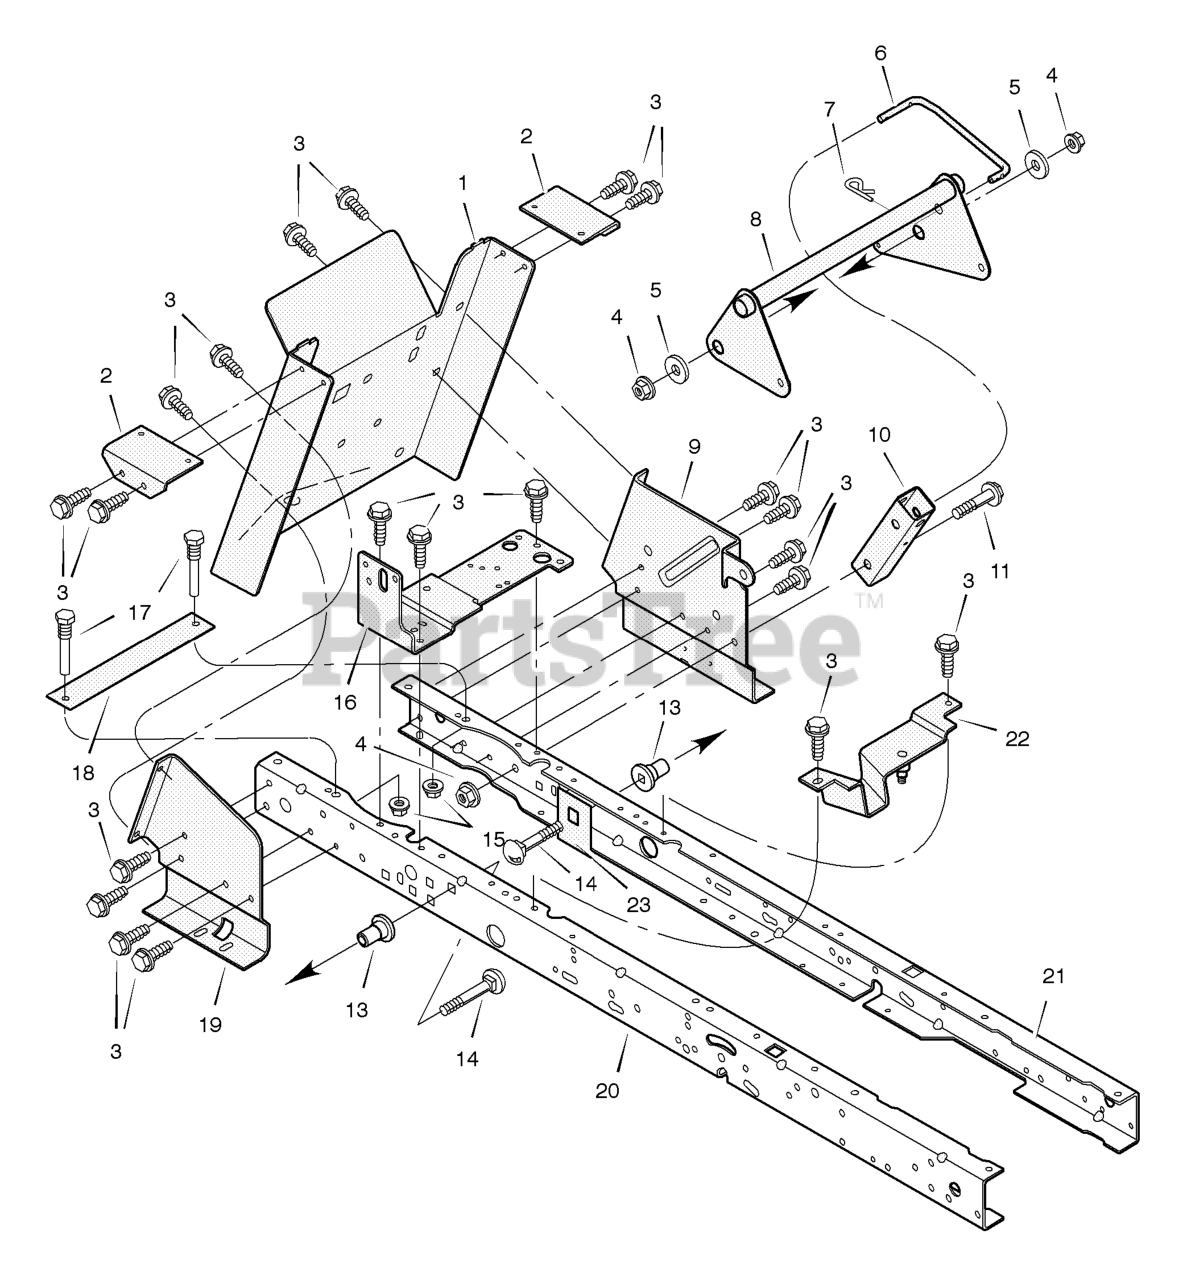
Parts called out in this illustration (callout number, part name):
1	Frame, Rear Hitch
2	Bracket, Seat Deck
4	Nut, Flange
6	Link, Lift Handle
7	Pin, Hair
8	Assembly, Lifter
9	Bracket, Left Transaxle
10	Bracket, Lift Pivot
11	Bolt, Shoulder
13	Spacer, Lifter
14	Bolt, Carriage
15	Nut, Flange
16	Bracket, Right Shift
17	Screw, Guide
18	Support, Battery
19	Bracket, Right Transaxle
20	Frame, Right
21	Frame, Left
22	Bracket, Idler
23	Plate, Stiffening
